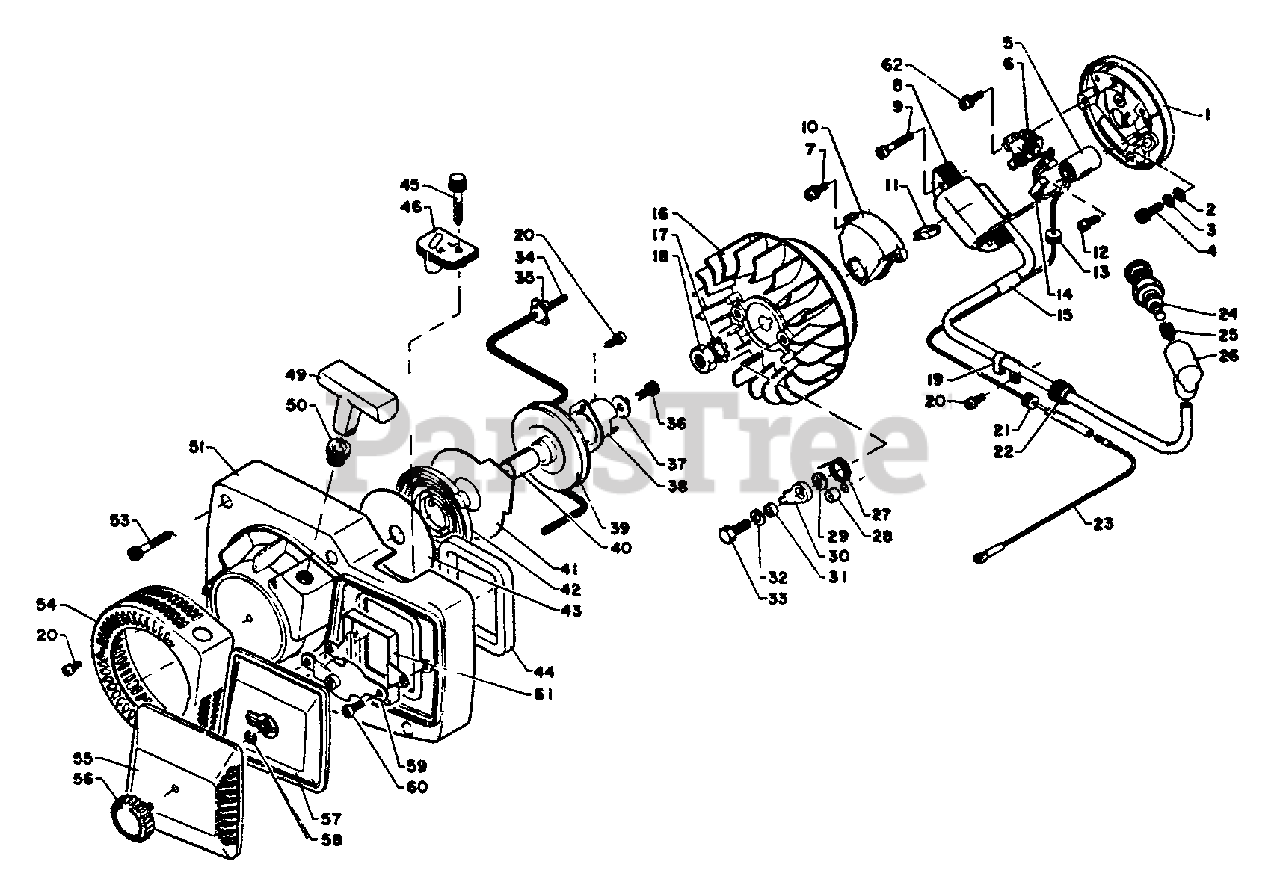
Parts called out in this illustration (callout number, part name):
1	PLATE, STATOR
2	WASHER, FLAT 5.5×10×0.8
3	WASHER, SPRING 5
4	SCREW - 5×15
5	CONDENSER
6	CONTACT POINT SET
7	SCREW 4×14
8	COIL, IGNITION
9	SCREW 4×25
10	COVER, BREAKER
11	PAD, OIL
12	SCREW - 4×10
13	GROMMET
14	GROMMET
16	FLYWHEEL
17	WASHER, LOCK
19	CLIP, CORD
20	SCREW 4×10
21	GROMMET
23	LEAD - GROUND
24	SPARK PLUG - BPM7A
25	TERMINAL, SPARK PLUG
26	CAP, SPARK PLUG
30	PAWL, STARTER
32	WASHER 6.5×11.5×0.8
33	BOLT 6×16
34	ROPE, STARTER
35	RETAINER, ROPE
36	BOLT 5×12
37	WASHER 5.2×16×1.0
38	PAWL CATCHER
39	REEL, ROPE
41	PLATE, STARTER
42	SPRING, RECOIL
43	PLATE, STARTER
44	GASKET, CARBURETOR CASE
45	SCREW, IDLE ADJUST
46	GROMMET
50	GUIDE, ROPE
51	CASE, STARTER
53	BOLT 5×30
54	FILTER, DEBRIS
55	COVER, AIR FILTER
56	THUMBSCREW
57	FILTER, AIR
58	E-RING 4
59	PLATE, PREVENT
60	SCREW 5×10
60	STARTER ASSY
60	STATOR ASSY
62	SCREW
